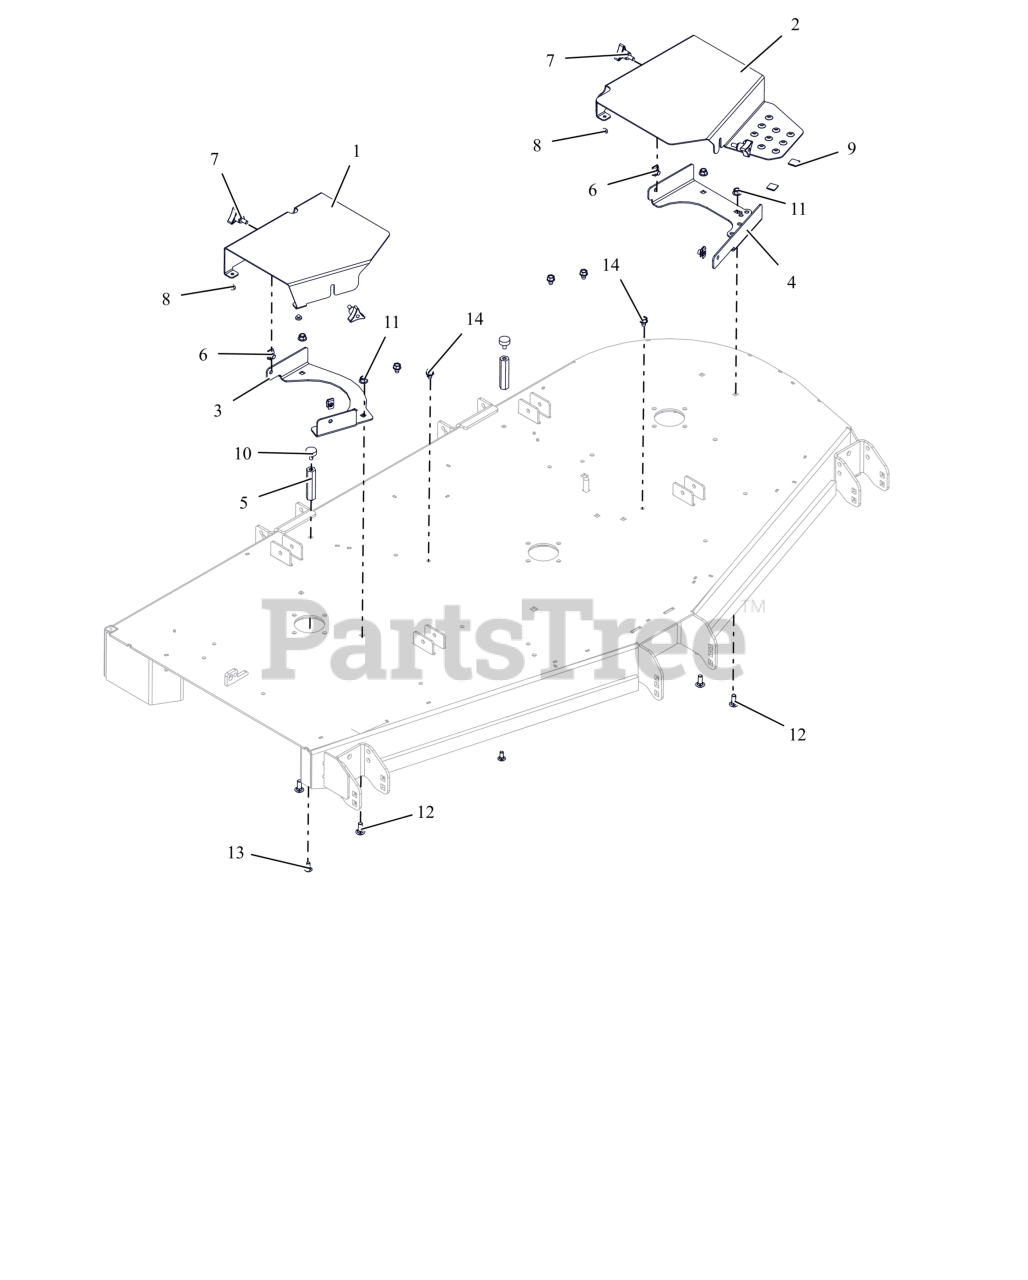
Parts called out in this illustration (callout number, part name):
1	GUARD, RH DECK - RED
2	GUARD, LH BELT - RED
3	BRKT, RH BELT GUARD MTG - RED
4	BRKT, LH BELT GUARD MTG - RED
5	NUT, COUPLING .312-18 X 3.250
6	NUT-CLIP RETAINER 5/16-18X.56
7	KNOB,WING STUD 5/16-18 X .75
8	BUMPER GROMMET
10	BUMPER, RUBBER
11	NUT,NYL-FLG .38-16 GF ZCC
12	BLT, RHSN .38-16X1.00 G5 ZCC
13	BTL,RHSN .313-18 X 0.75 G5 ZCC LT
14	SCR,TAP .375-16X.50 HWH TR ZCC
